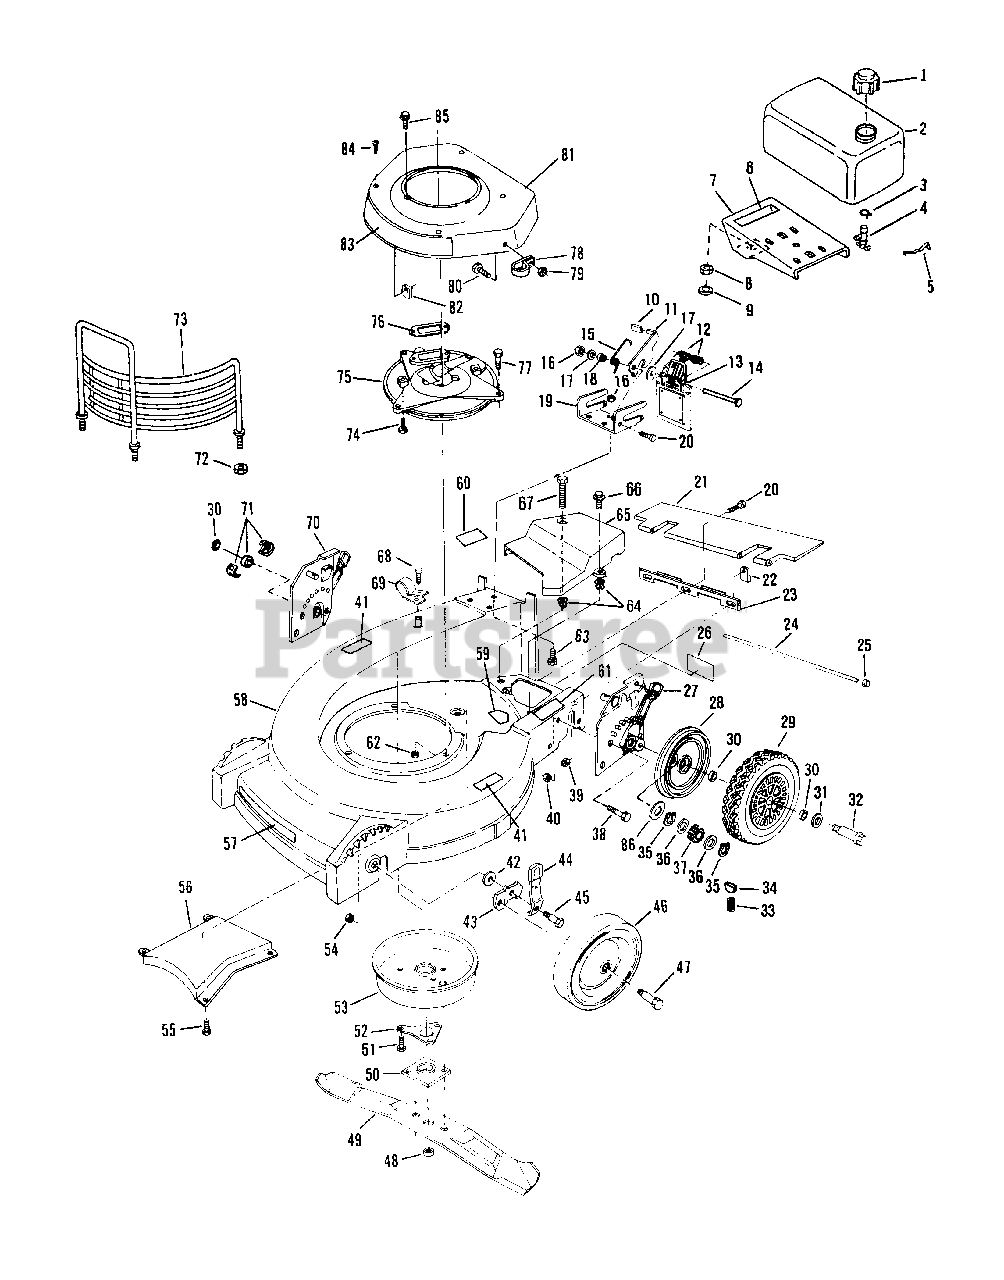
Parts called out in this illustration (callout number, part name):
1	Fuel Cap
2	Fuel Tank
3	Clamp
4	Shut-Off Valve and Screen
5	Spring-Fuel Tank Mounting
6	Decal-Fuel Mixture
7	Bracket-Fuel Tank
8	Nut-Tank Mounting
9	Washer-Tank Mounting
10	Knob-Latch
11	Latch-Bag
12	Spring
13	Door
14	Rod
15	Spring-Latch
16	Nut
17	Washer
18	Stepped Spacer
19	Hinge Plate
20	Screw-Latch Mounting and Trailing Shield
21	Trailing Shield
22	Clamp-Rod
23	Bracket-Bag Support
24	Rod-Trailing Shield
25	Nut-Rod
26	Decal-Caution
27	Height Adjust Assembly-L.H.
28	Cover-Wheel
29	Wheel-Rear
30	Washer-Felt
31	Washer-Rear Wheel
32	Screw-Rear Wheel
33	Spring
34	Key
35	Retaining Ring
36	Spacer
37	Pinion
38	Screw-Handle Bracket to Housing
39	Nut-Bag Support Bracket
40	Nut-Handle Bracket to Housing
41	Decal-Cutting Height
42	Washer Height Adjust
43	Bracket-Wheel Height Adjust
44	Knob and Spring Assembly
45	Bolt-Shoulder
46	Wheel-Front
47	Bolt-Front Wheel
48	Nut-Blade
49	Blade-20"
50	Collar and Plate Assembly
51	Screw-Muffler Cover to Plate
52	Support-Crankshaft
53	Muffler Cover Assembly
54	Nut-Wheel Height Adjust
55	Screw
56	Baffle
57	Decal-Headliner
58	Housing-20" Assembly
59	Decal-Blade Contact
60	Decal-Commercial Mower
61	Decal-Commercial Safety Warning
62	Nut
63	Screw
64	Grommet-Belt Cover
65	Belt Cover
66	Screw-Belt Cover
67	Screw-Hex Head
68	Screw-Clamp to Housing
69	Clamp-Cable to Housing
70	Height Adjust Assembly-R.H.
71	Bearing and Retainer Assembly
72	Nut-Guard Mounting
73	Engine Guard Assembly
74	Screw-Muffler Plate to Block
75	Plate-Muffler
76	Gasket-Exhaust
77	Screw-Muffler Plate to Housing
78	Clamp-Throttle Cable to Shroud
79	Nut
80	Screw
81	Shroud and Nut Assembly
82	Retainer-Applique
83	Applique-Shroud
84	Screw-Shroud Mounting
85	Screw-Starter Mounting
86	Washer
